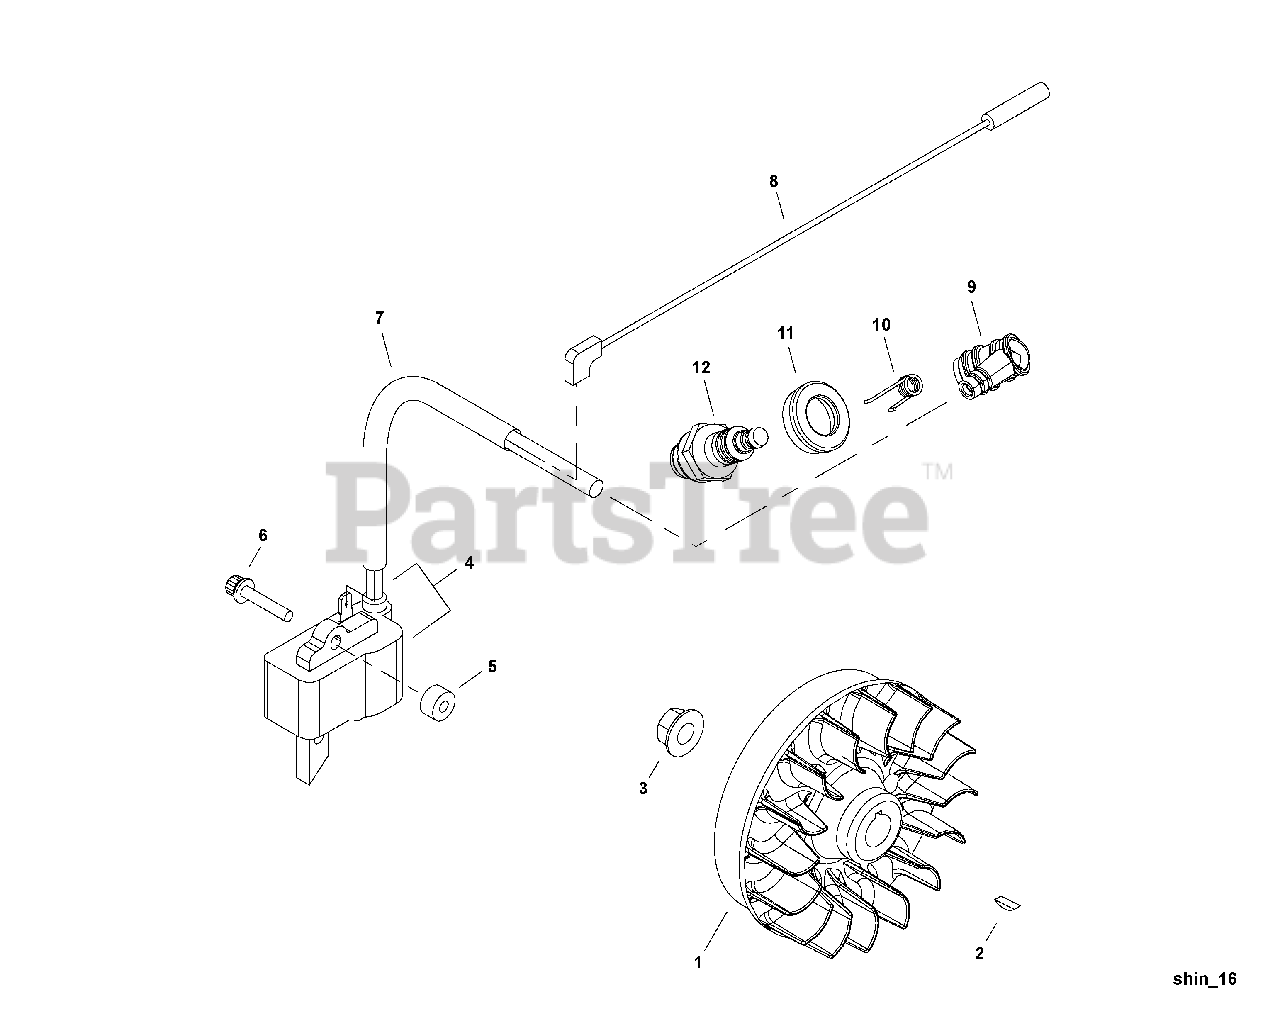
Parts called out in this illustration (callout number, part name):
1	FLYWHEEL
2	KEY, WOODRUFF 3×10
3	NUT M8
4	COIL, IGNITION
5	INSULATOR 4.2×11×6
6	BOLT, ADHESIVE M4×20
7	TUBE, IGNITION COIL
8	LEAD - IGNITION L= 215
9	CAP, SPARK PLUG
10	TERMINAL, SPARK PLUG
11	SEAL, SPARK PLUG
12	SPARK PLUG - BPMR6A
